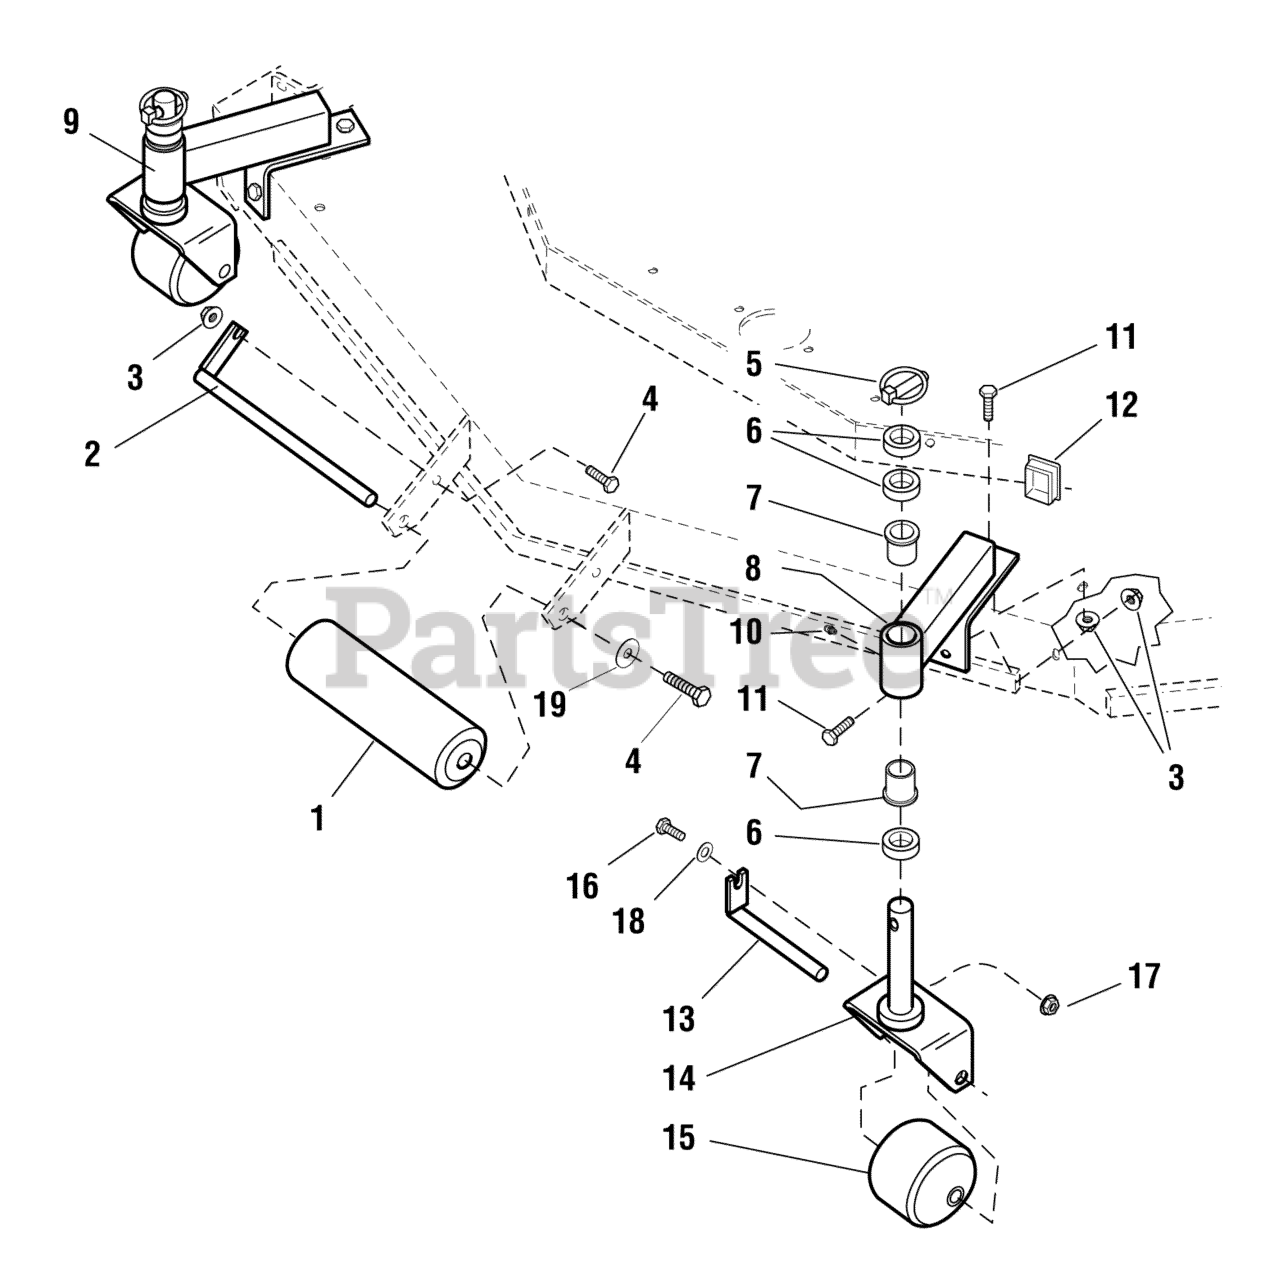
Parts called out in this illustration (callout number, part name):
1	ROLLER, DECK
3	NUT, 3/8-16 HEX NYLOCK FLANGE
4	BOLT, 3/8-16 X 1" GD5 CZ
5	PIN, LYNCH, 7/16
6	SPACER, 1.02 X 1.56 X .50
7	BUSHING, FLANGE
8	ASSM, ARM, DECK CASTER, LH
9	ASSM, ARM, DECK CASTER, RH
10	GREASE FITTING, 1/4-28 STRAIGHT
11	BOLT, 3/8-16 X 3/4" GD5 CZ
12	CAP, 1-1/2 X 2 X 11GA, PLASTIC
13	WELD, CASTER ROLLER PIN
14	WELD, CASTER YOKE
15	ROLLER, SMALL
16	BOLT, 5/16-18 X 3/4 GD5
17	NUT, 5/16-18 HEX SERRATED FLANGE (SMALL)
18	WASHER, 5/16 GD.9 FLAT
19	WASHER, .390 X 1.50 X .109 YZ
